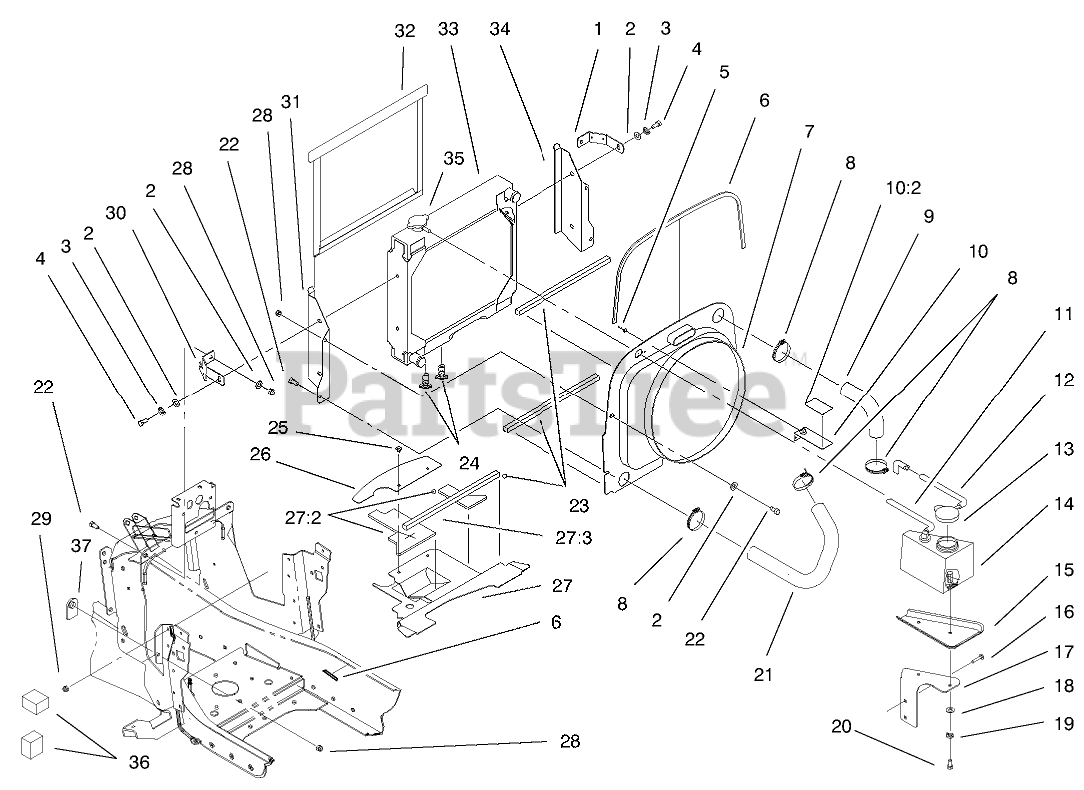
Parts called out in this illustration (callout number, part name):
1	Strap-Radiator
2	WASHER-PLAIN
3	WASHER-LOCK
4	SCREW-HH
5	RIVET-POP
5:2	FILTER
5:3	COVER ASM
5:3:1	Latch-Air Cleaner
5:4	VALVE-VACUATOR
5:5	PLUG-PIPE
6	Trim-Loc
6	TRIM - LOC 31"
7	SHROUD - FAN
8	CLAMP-HOSE
9	HOSE - RAD. DAIHATSU
10	FAN/DECAL ASM
10:2	DECAL - WARNING
11	HOSE - FUEL LINE
12	HOSE - OVERFLOW
12:1	HEAD ASM
12:2	VENT-AIR
12:3	ELEMENT-SPIN ON
12:4	VALVE-DRAIN
13	CAP - COOLANT RESERVOIR
14	BOTTLE - OVERFLOW
15	TRAY - OVERFLOW
16	BOLT-CARR
17	Brkt-Bottle
18	WASHER-FLAT
19	WASHER-LOCK
20	SCREW-HH
21	HOSE - RAD. DAIHATSU
22	SCREW-HH
23	FOAM - RADIATOR/SHROUD
24	VALVE - DRAIN
25	RIVET - PLASTIC
26	BAFFLE - TOWER REAR
27	BAFFLE-TOWER ASM
27:2	FOAM - BAFFLE
27:3	FOAM - RADIATOR/SHROUD
28	NUT-LOCK, NI
29	NUT-HEX
30	Bracket-Relay
31	Support-Radiator RH
32	SCREEN - CHAFF
33	RADIATOR - DIESEL
34	Support-LH Radiator
35	CAP-RADIATOR
36	SEAL-FOAM, SIDE
37	WASHER - SPACER
